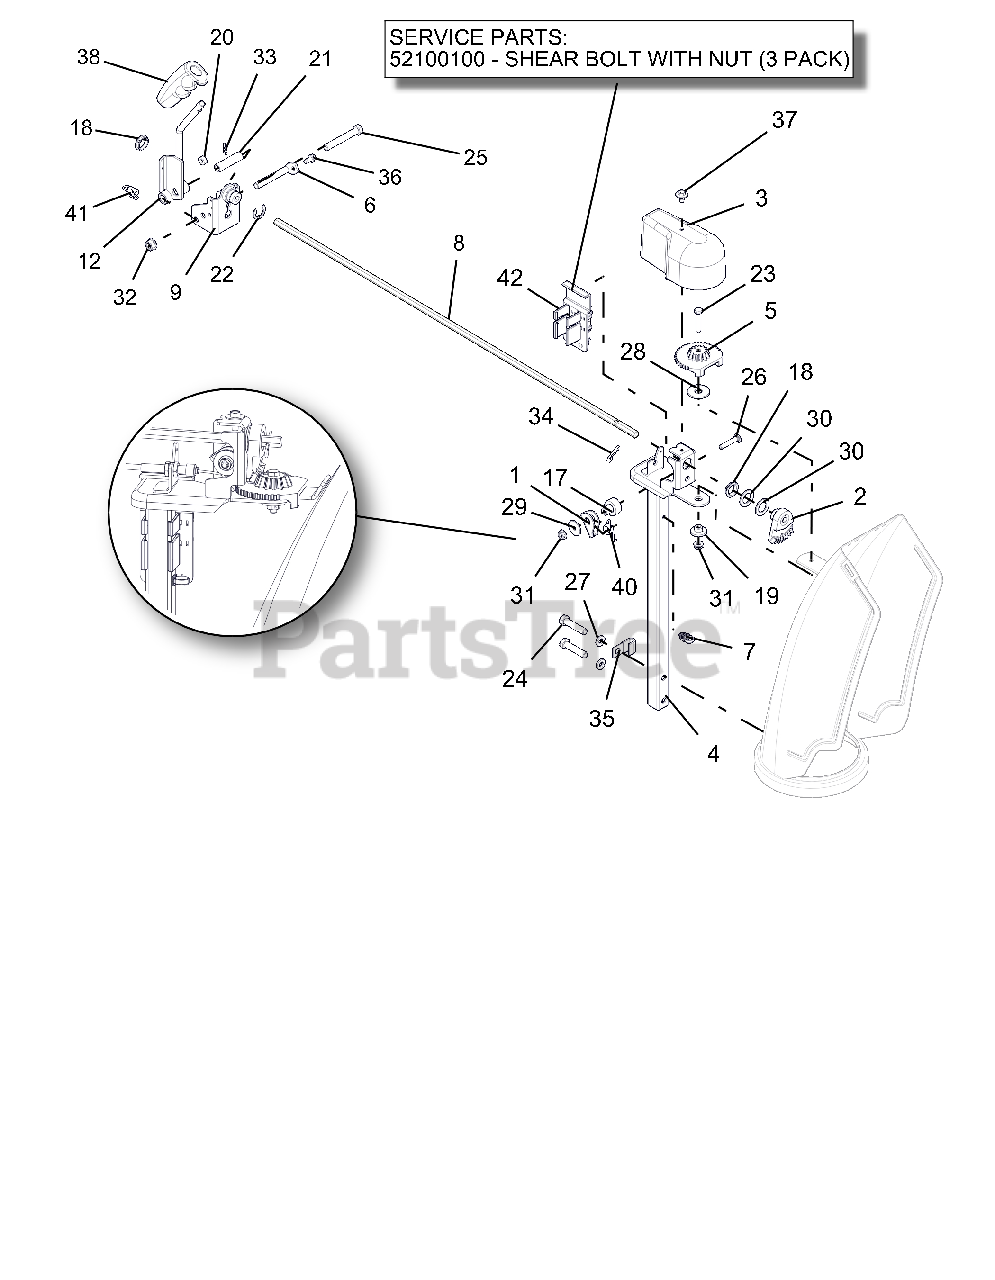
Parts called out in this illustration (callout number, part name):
1	ARM, LOCKING
2	GEAR, CHUTE-ACTUATION
3	COVER, CHUTE GEAR
4	PEDESTAL, CHUTE - QUICK STICK
5	GEAR, CHUTE
6	ROD, PIVOT - INTERLOCK
7	CLIP, CABLE GUIDE
8	ROD, HEX - CHUTE ROTATION
9	WELDMENT-CONTROL BRACKET-CHUTE
12	WELDMENT, CONTROL LEVER
17	BUSHING, LOCK ARM
18	BUSHING, POLYLINER-.75 SNAPIN
19	BSHG-FLG .265X.477X.375X1.00
20	BSHG-SLV .265X.500X.219
21	SPCR, WHEEL .385X.500X2.00
22	E-RING .750X.050
23	@BLT-HEX .25-20X1.50 GR5 YWZC
24	@BLT-HEX .38-16X1.75 GR5 YWZC
25	@BLT-HEX .38-16X2.75 GR5 YWZC
26	@BLT-RDHDSQNK .25-20X1.50 G5YZ
27	@WSHR-LK .38X.094 REG YWZC
28	WSHR-FLT-NYL .515X1.375X.093
29	WSHR-FL-STL .281X1.000X.063
30	WSHR-FL-STL.754X1.125X.062YWZC
31	@NUT-LK-CTR-FLG .25-20 YWZC
32	@NUT-LK-TOP-FLG .38-16 YWZC
33	PIN-HAIR INT .06X.18X.77
34	PIN-HAIR INT .08X.18X1.18 YWZC
35	J-CLAMP
36	SCR-TAP .25-20X.50 HWH TR YWZ
37	SCR-TAP .25-20X.50 LGHWH TR YZ
38	CONTROL HANDLE, QUICK TURN
39	PIN-WELD .25X.625
40	SG-TORS
41	SPRING-EXT .047X.438X1.45
42	HOLDER W LARGE SHEAR BOLT /NUT
42	SHEAR BOLT SERVICE ASSEMBLY
